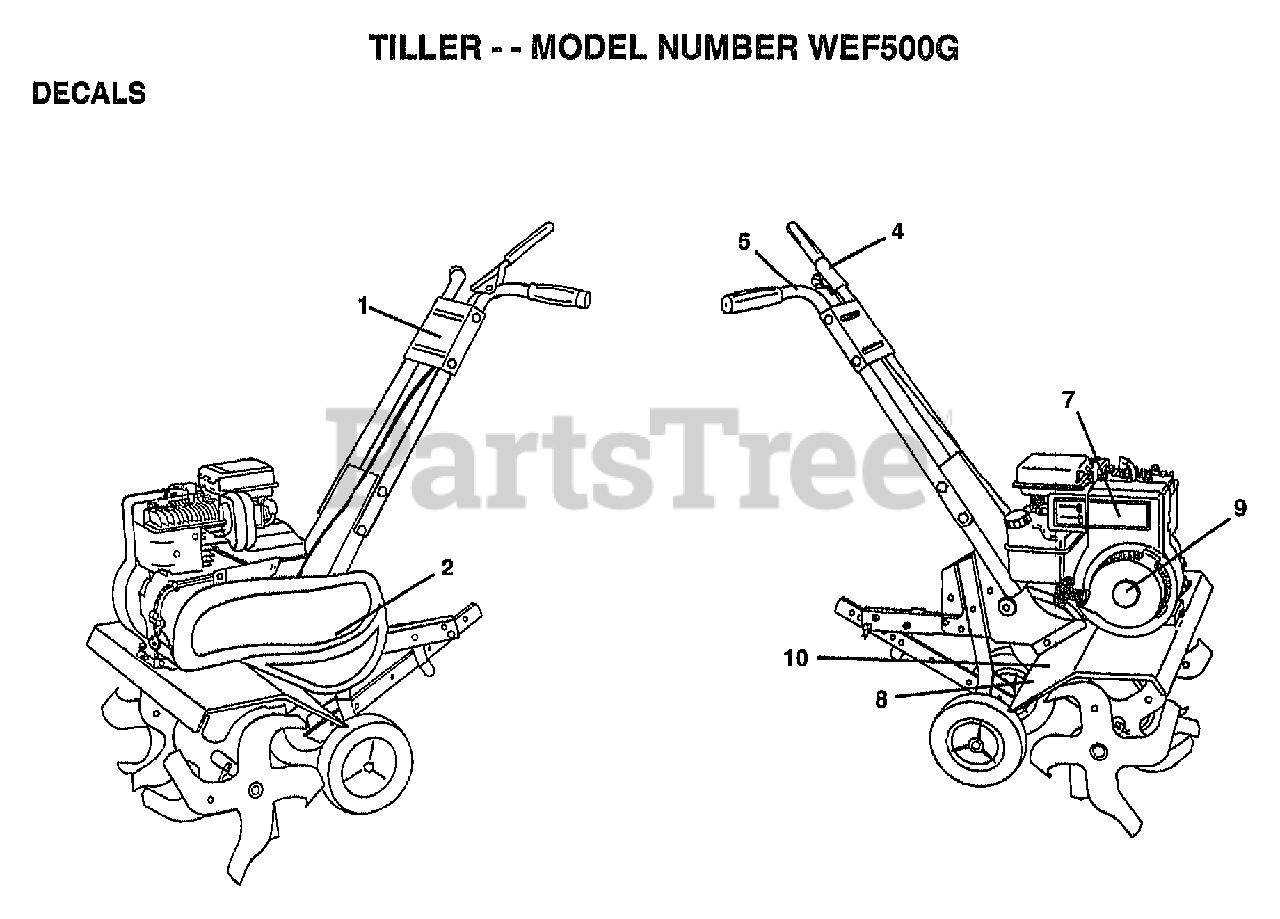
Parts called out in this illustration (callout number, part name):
1	DECAL.LOGO.CONTROL
4	DECAL TI
5	DECAL TI
10	DECAL.CAUTION
